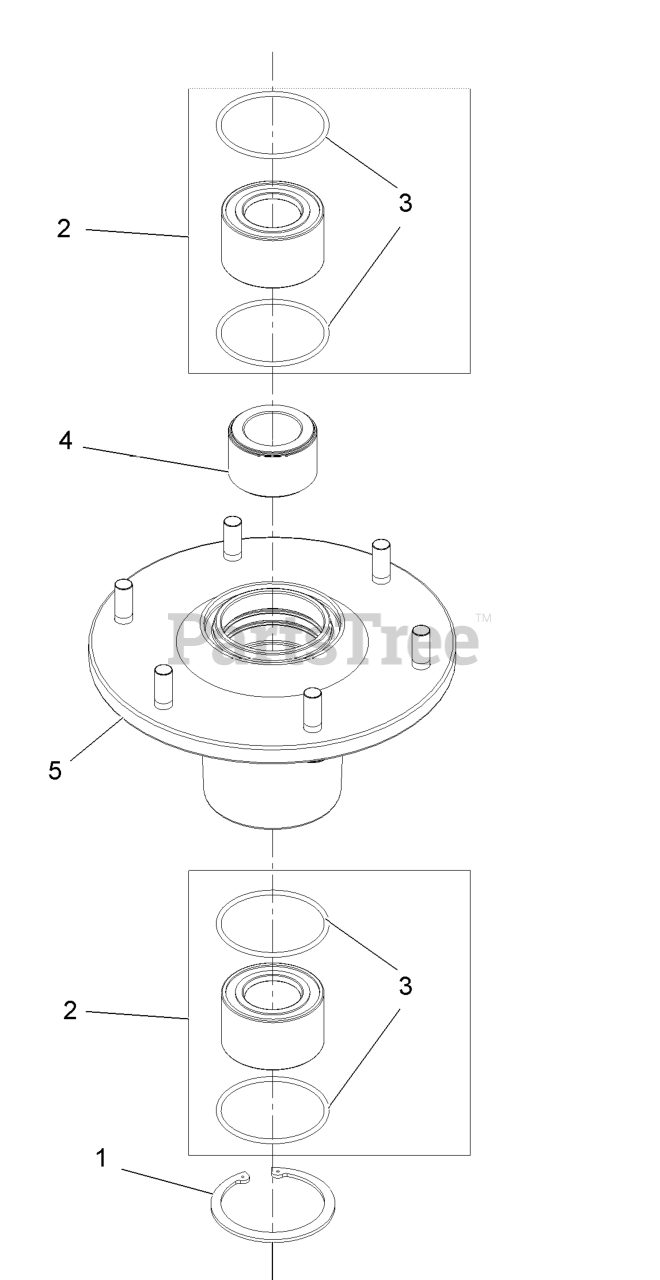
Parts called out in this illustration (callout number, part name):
1	RING-RETAINING
2	ASM, BEARING W/ORINGS
4	SPACER,BEARING
5	ASM,HOUSING W/STUDS
